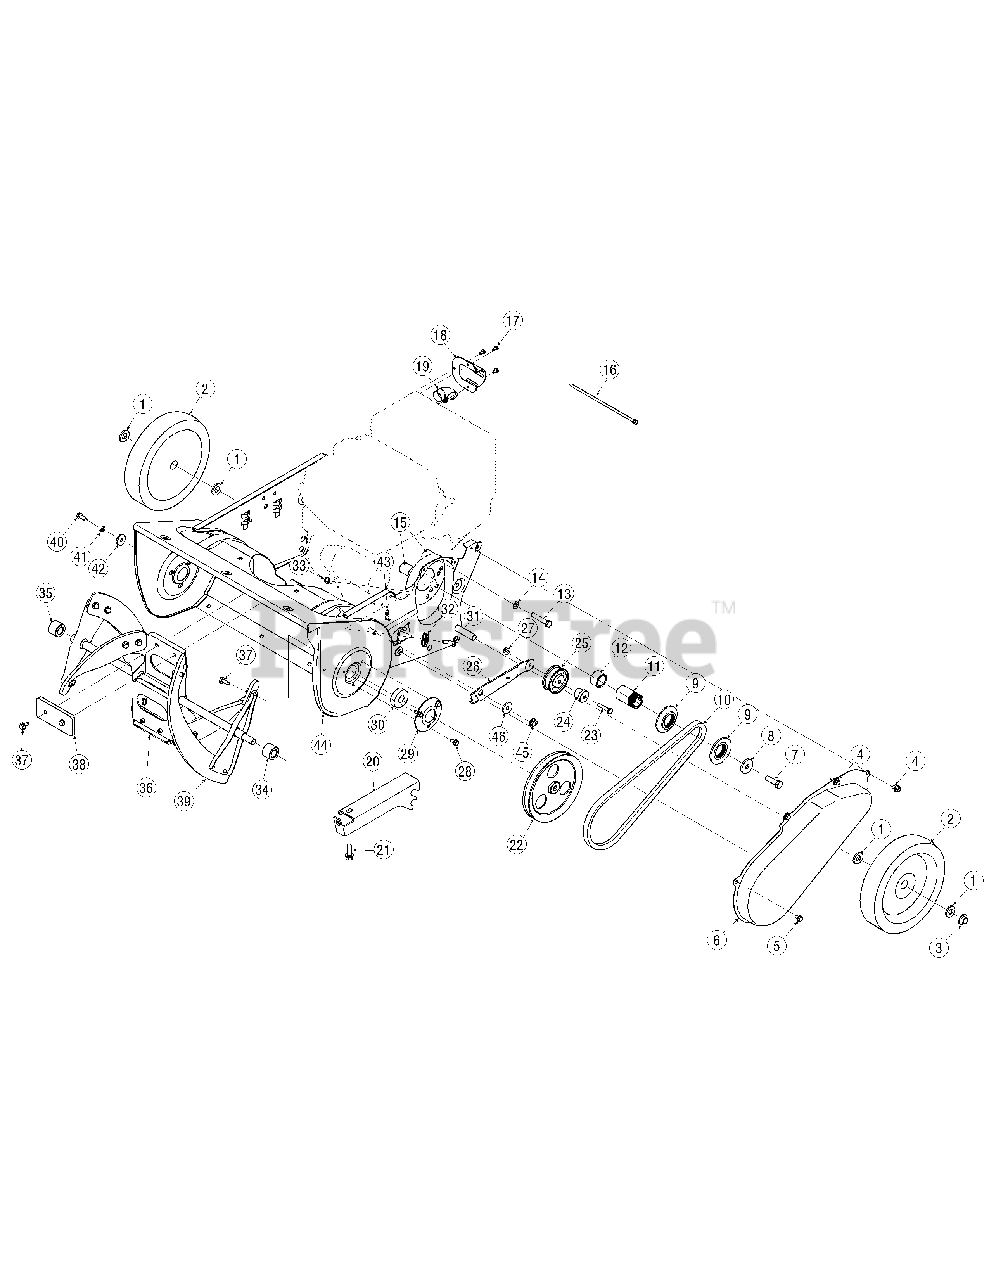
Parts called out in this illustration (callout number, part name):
1	Flat Washer, .510 x 1.000 x .125
2	Wheel, 8 x 1.7
3	Push Cap, 1/2"
4	Hex Screw, 1/4-14 x .625
5	Hex Screw, 1/4-20 x .375
6	Belt Cover
7	Hex Screw, 3/8-24 x 1.75
8	Flat Washer, .406 x 1.25 x .157
9	Pulley Half, 4L-V x .240 OD
10	V-Belt
11	Spacer, .875 ID x 1.185 OD
12	Spacer, .88 ID x 1.18 OD x .74
13	Hex Bolt, 5/16-24 x 1.75
14	Lock Washer, 5/16
15	Spacer, .875 x .320 x 1.027
16	Cable Tie, 7.5"
17	Hex Screw, #8-32 x .375
18	Heat Shield
19	Exhaust Tube
20	Engine Support Bracket
21	Hex Screw, 3/8-16 x 1.000
22	Pulley, 1/2 x 6.00 OD
23	Hex Screw, 1/4-20 x 1.25
24	Shoulder Spacer, .260 x .785 x .538
25	Idler Pulley Assembly, 1.917 OD
26	Idler Bracket
27	Flange Lock Nut, 1/4-20
28	Hex Screw, 1/4-14 x .500
29	Bearing Cap
30	Ball Bearing, .625 x 37 x 12 x .6301
31	Shoulder Screw, 1/4-28 x .340 x .335
32	Cable Roller
33	Hex Lock Nut, 1/4-28
34	Auger Spacer, LH
35	Auger Spacer, RH
36	Auger Assembly, 21" (Incl. 37, 38 & 39)
37	Hex Screw, 1/4-14 x .625
38	Rubber Paddle
39	Spiral Crescent
40	Hex Screw, 1/4-20 x .750
41	Lock Washer, 1/4
42	Flat Washer, .265 x .938 x .120
43	Extension Spring, .33 OD x 1.12
44	Auger Housing, 21"
45	Flange Lock Nut, 5/16-18
46	Shoulder Spacer
